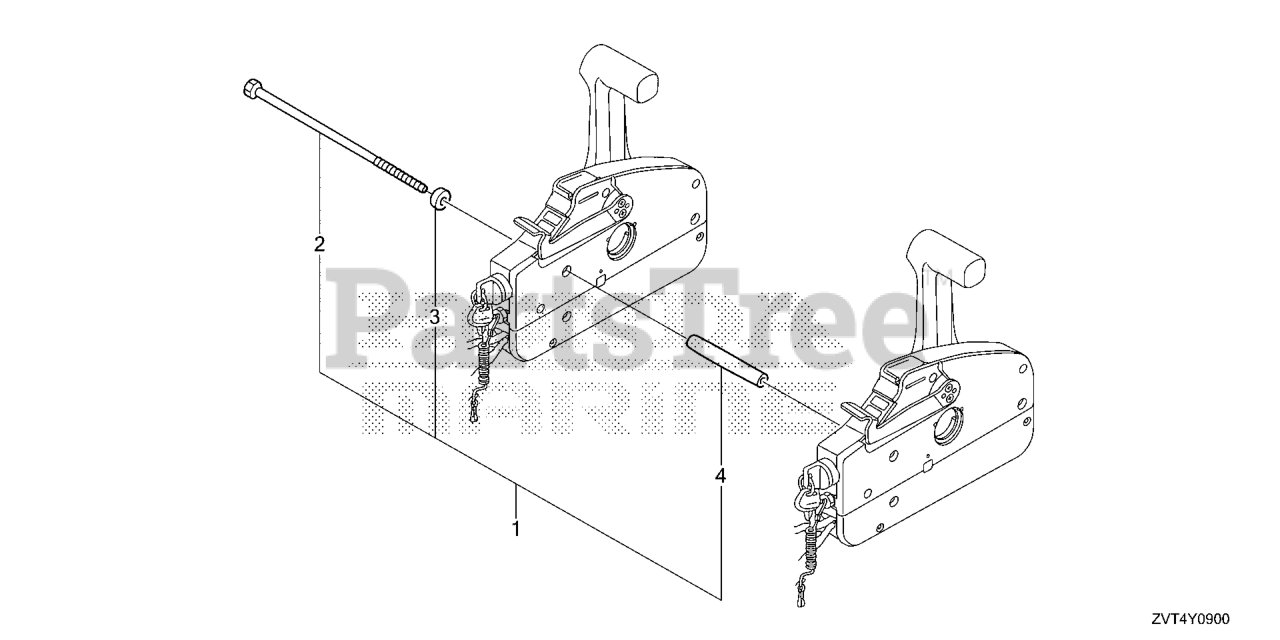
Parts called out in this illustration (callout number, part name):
1	BOLT KIT, SIDE REMOTE CONTROL
2	BOLT, SPECIAL (6X220)
3	COLLAR, DISTANCE (A)
4	COLLAR, DISTANCE (B)
